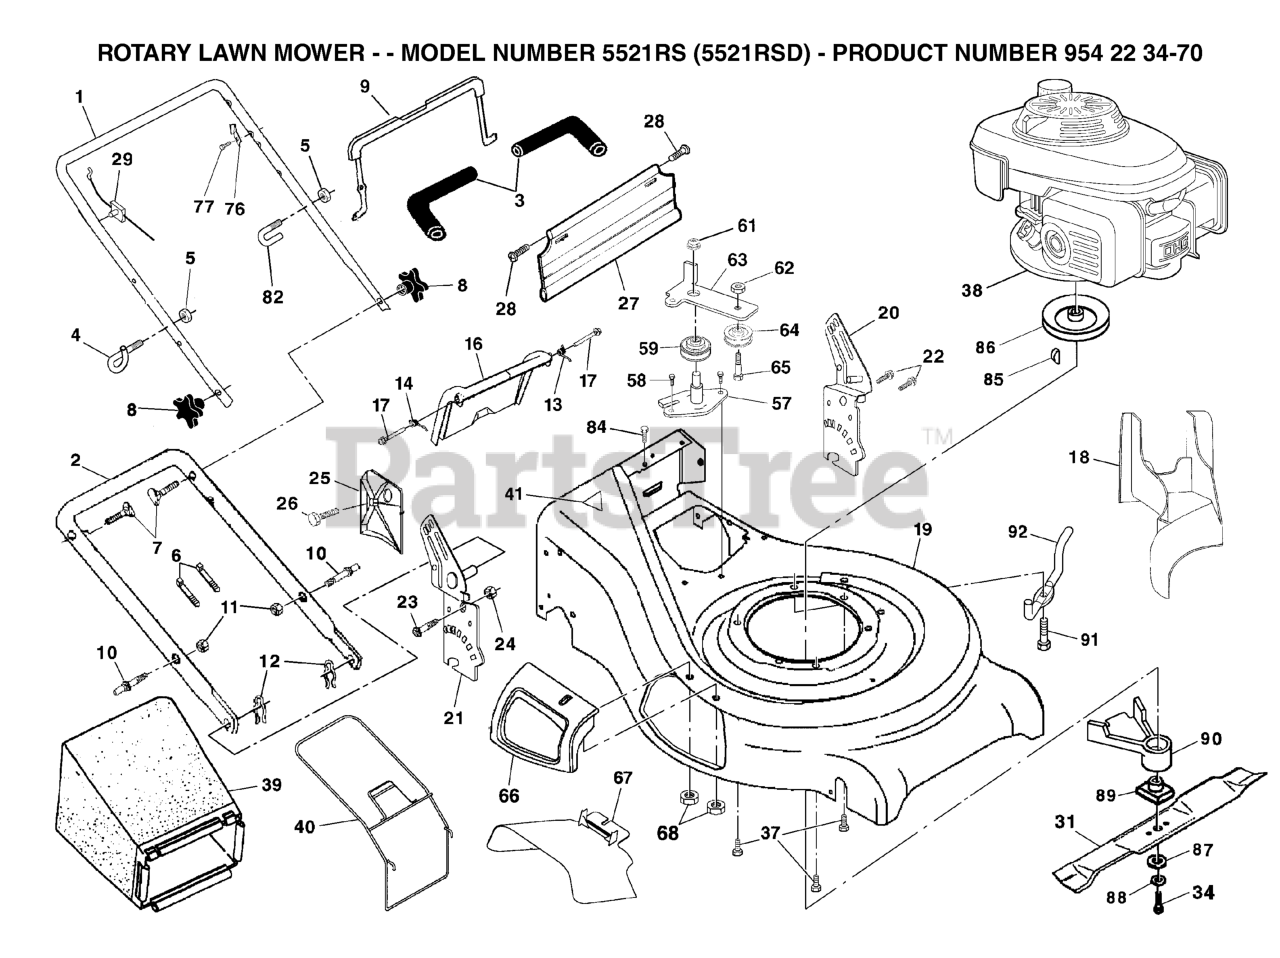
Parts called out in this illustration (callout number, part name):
1	HANDLE.UP.ASM.DSTRT/FLT
2	HANDLE, LOWER
3	GRIP.HANDLE.FOAM.WIDE.(1 SIDE)
4	ROPE, GUIDE
5	NUT
6	TIE GUIDE
7	HANDLE BOLT
8	KNOB.HANDLE.STAR.HUSQ.GRAY
9	BAIL, FLAT AUTO WALK
11	NUT.CENTERLOCK.5/16-
12	HAIRPIN COTTER
13	SPRING.RH.REAR.DOOR.21.RWGD
14	SPRING.LH.REAR.DOOR.21.RWGD
16	DOOR.REAR.PLASTIC.21.RWGD.BLAC
18	PLUG, MULCHER
19	RP KIT.HSG.21.RGD.MC.ORAN
20	HANDLE BRACKET ASM. LH
21	HANDLE BRACKET ASM. RH
22	SELF-TAPPING SCREW 5/16-18X3/4
23	BOLT, HEX HEAD 5/16-18
24	NUT.71038.31-18.HEX.NYLOCK
25	CLIPPING DEFLECTOR
27	SKIRT, REAR
28	HINGE SCREW
29	ENGINE ZONE CONTROL CABLE
31	BLADE.21.PUSH/RWGD/FWG
34	SCREW, HEX HD 3/8-24 X 1-3/8
37	BOLT 3/8-16X1-1/8
39	GRASS CATCHER BAG
40	GRASS CATCHER FRAME
41	DECAL HYT
57	BRACKET ASSEMBLY
59	PULLEY ASSY
61	NUT
62	LOCKNUT
63	IDLER ARM
64	IDLER PULLEY
65	SHOULDER BOLT
66	MULCHER DOOR ASM.
67	DEFLECTOR, DISCHARGE
76	BRACKET UPSTOP
85	HI-PRO KEY
86	PULLEY.ENG.25MMM
87	WASHER,HARDEN
88	LOCKWASHER
89	BLADE ADAPTER
90	DEBRIS SHEILD
91	SCREW
92	BRACKET
